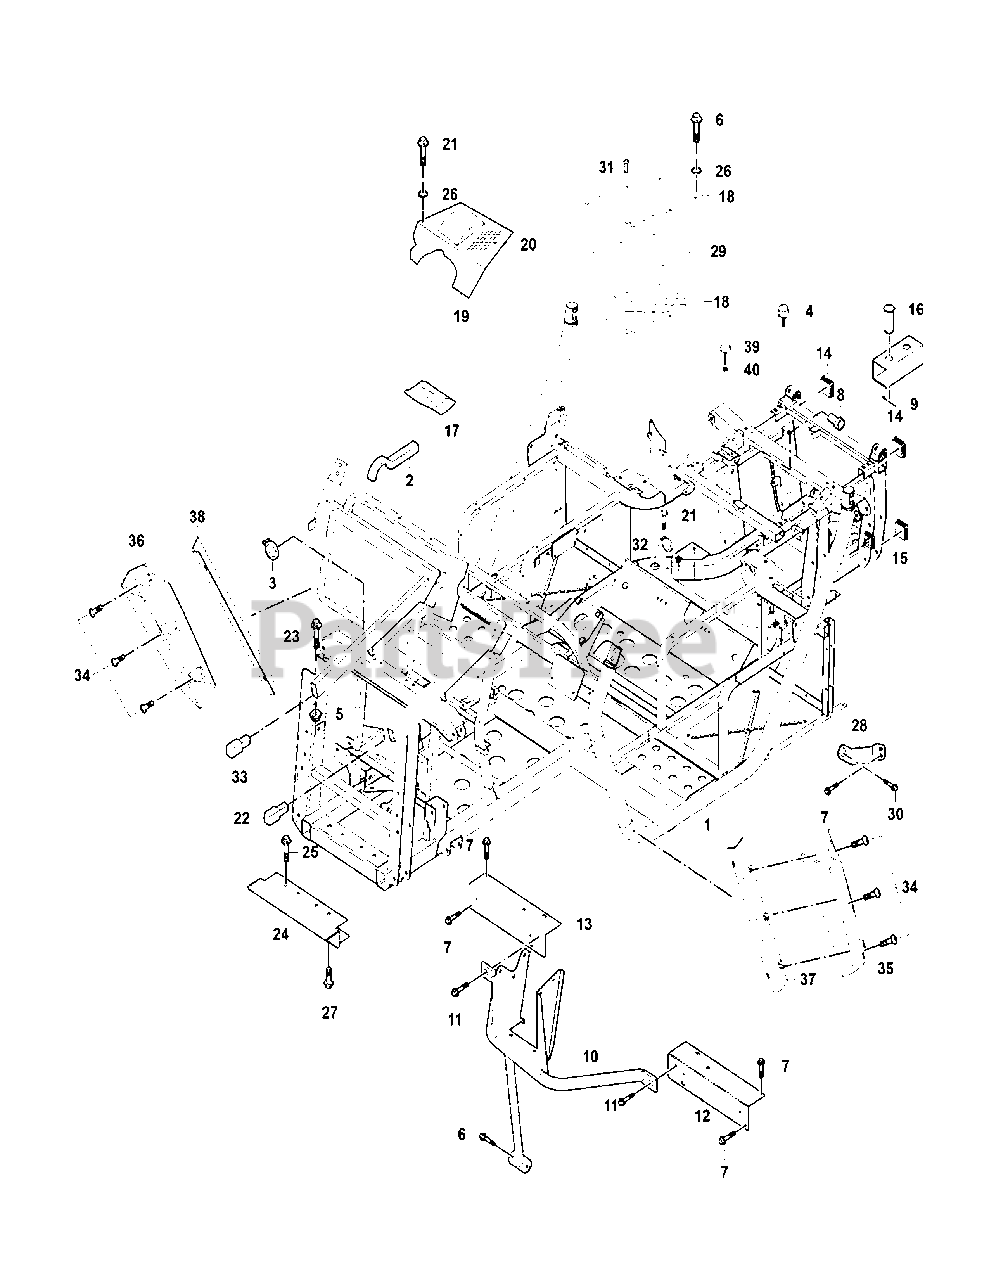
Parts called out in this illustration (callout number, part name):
1	Frame joint parts
2	Shock absorber adjusting wrench
3	Clip9
4	Rubber Cushion (Round)24-28
5	Hexagon flange nut M10×1.25
6	Hexagon Flange Bolt M6×16
7	Hexagon Flange Bolt M8×16
8	Shock Absorber Cushion 24-11
9	R type pin24
10	Middle protective bracket
11	Hexagon flange bolt M10×1.25×25
12	Bracket, left seat
13	Bracket, right seat
14	Frame Pipe Plug 40×25
15	Frame Pipe Plug 60×40
16	Hitch Bar Pin
17	Tool kit
18	Insulation board, muffler
19	Insulation board, rear bridge
20	Insulation paper i
21	Hexagon Flange Bolt M6×16
22	Mounting bracket, front body cover
23	Hexagon Bolt M10×1.25×55
24	Bumper holder
25	Hexagon flange bolt M12×1.25×35
26	Washer6×18×1.6
27	Hexagon flange bolt M12×1.25×25
28	Lower installing support, rear bridge
29	Heat Inslation Foam
30	Hexagon flange bolt M10×1.25×20
31	Screw 3.2×11
32	Clip , metal water pipe
33	Mounting bracket, front body cover
34	Cross large plate head screw M6×16
35	Left fender, front cover II
36	Right fender, front cover II
37	Mounting Bracket, Left Fender
38	Mounting Bracket, Right Fender
39	Adjust Damping Washer
40	Nut M8
